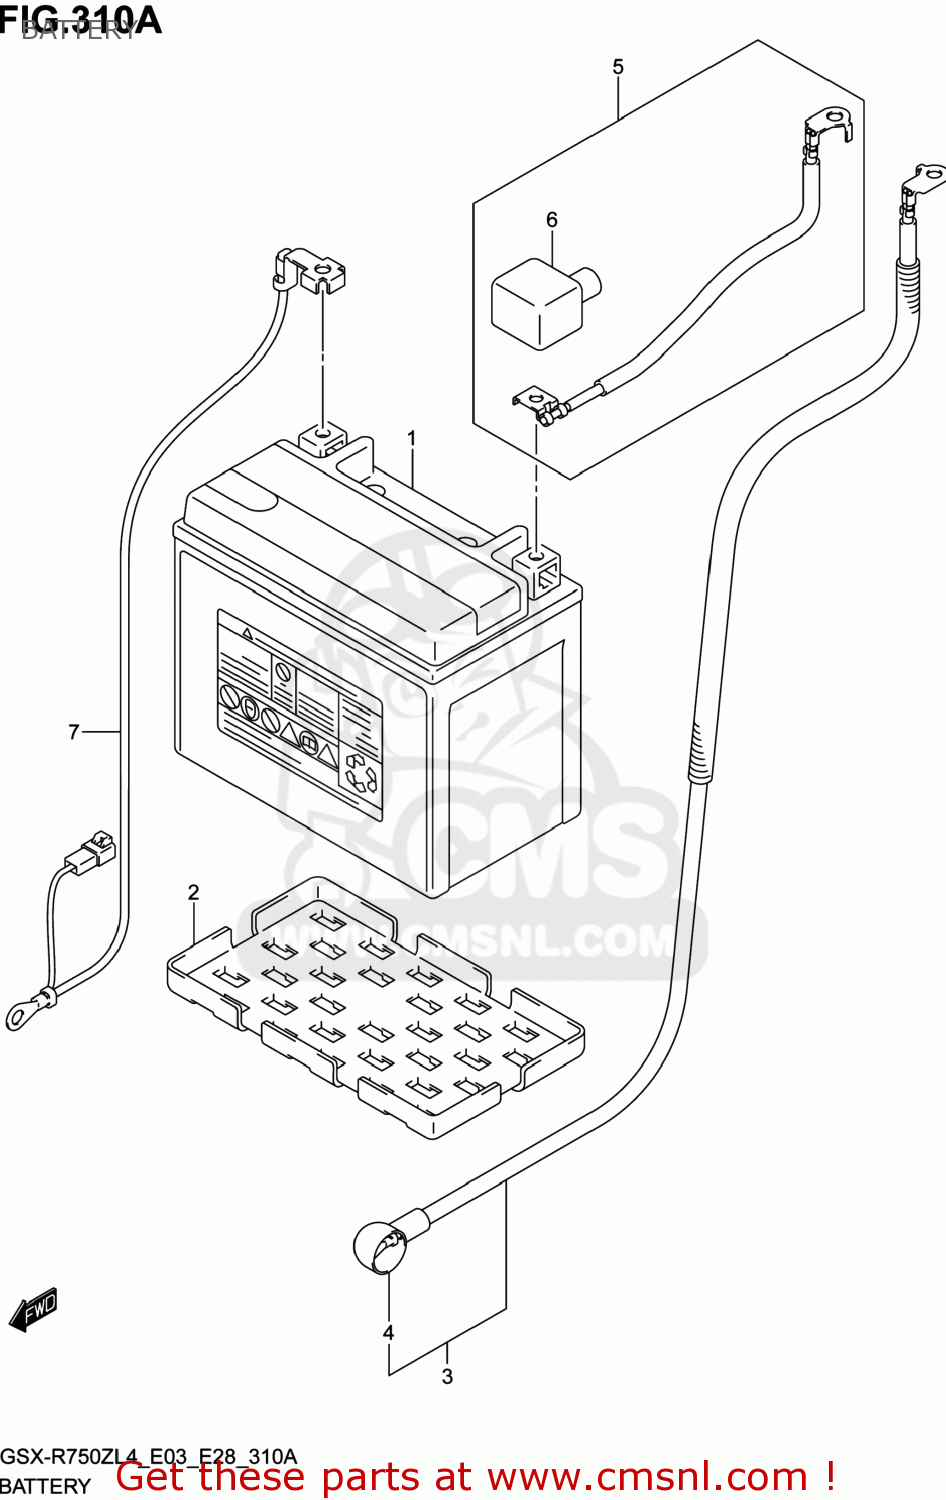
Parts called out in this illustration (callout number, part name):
1	BATTERY ASSY(FT12A-BS,12V10AH)
2	PROTECTOR,BATTERY
3	WIRE,STARTER MOTOR LEAD
4	CAP,STARTER MOTOR
5	WIRE,BATTERY PLUS LEAD
6	CAP,BATTERY PLUS
7	WIRE,BATTERY MINUS LEAD
